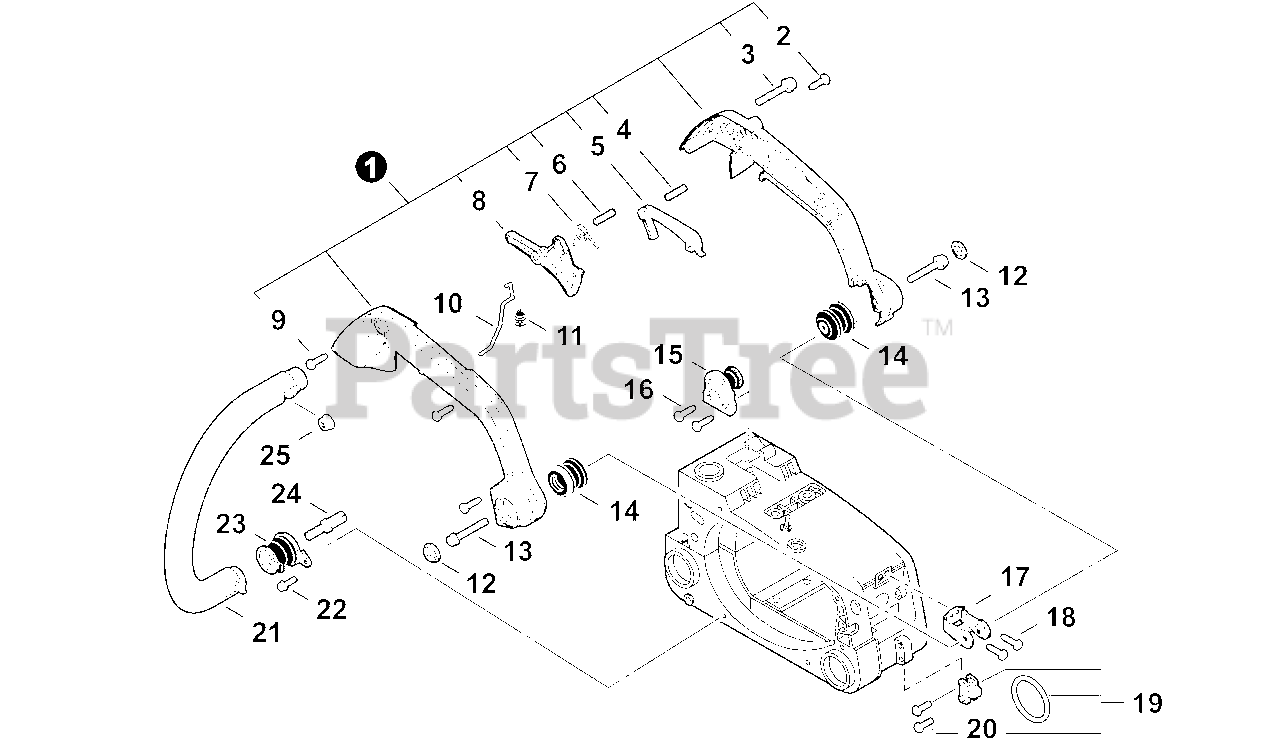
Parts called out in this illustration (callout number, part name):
1	HANDLE SET, REAR
2	SCREW 5×14
3	SCREW 5×35
4	PIN, SPRING 4×20
5	LOCKOUT, THROTTLE
6	PIN, SPRING 4×25 SUS
7	SPRING, TORSION
8	TRIGGER, THROTTLE
9	SCREW 4×16
10	ROD, THROTTLE
11	GROMMET, THROTTLE ROD
12	CAP, CUSHION
13	SCREW 4×10
14	CUSHION 4
15	CUSHION 5
16	SCREW 4×14
17	BRACKET, HANDLE
18	SCREW 4×14
19	HANGER SET, HARNESS
20	SCREW 4×16
21	HANDLE, FRONT
22	SCREW 4×16
23	CUSHION 5
25	NUT, FLANGE M5
